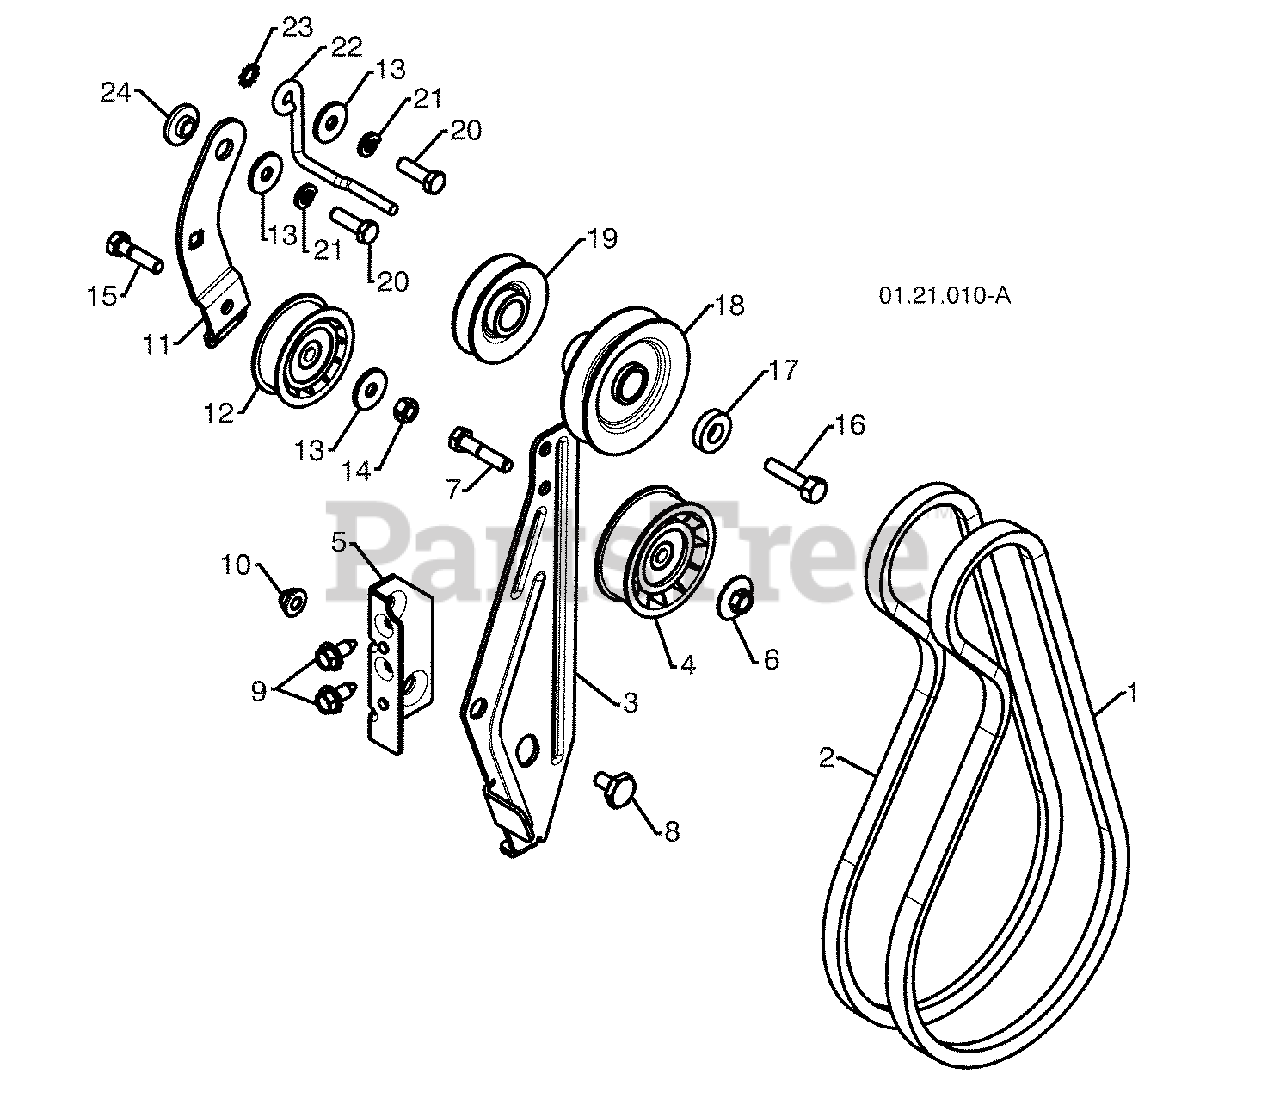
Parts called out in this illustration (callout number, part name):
1	IMPELLER BELT
2	TRACTION BELT
3	IDLER ARM BRACKET
4	IDLER PULLEY
5	IDLER BRACKET
6	NUT 5/16-18
7	SCREW 5/16-18 X 1.50
8	SHOULDER BOLT 5/16-18 X .50
9	SCREW 5/16-18 X .625
10	NUT 5/16-18 NYLOCK
11	TRACTION IDLER BRACKET
12	TRACTION PULLEY
14	NUT 5/16-18
15	SCREW 5/16-18 X 1.25
16	SCREW 3/8-24 X 1.375
18	PULLEY ENG IMPELLER
19	PULLEY ENG TRACTION
20	SCREW 5/16-24 X 1.00
21	LOCKWASHER 5/16
22	BELT GUIDE
23	LOCKWASHER 5/16
24	IDLER BUSHING
